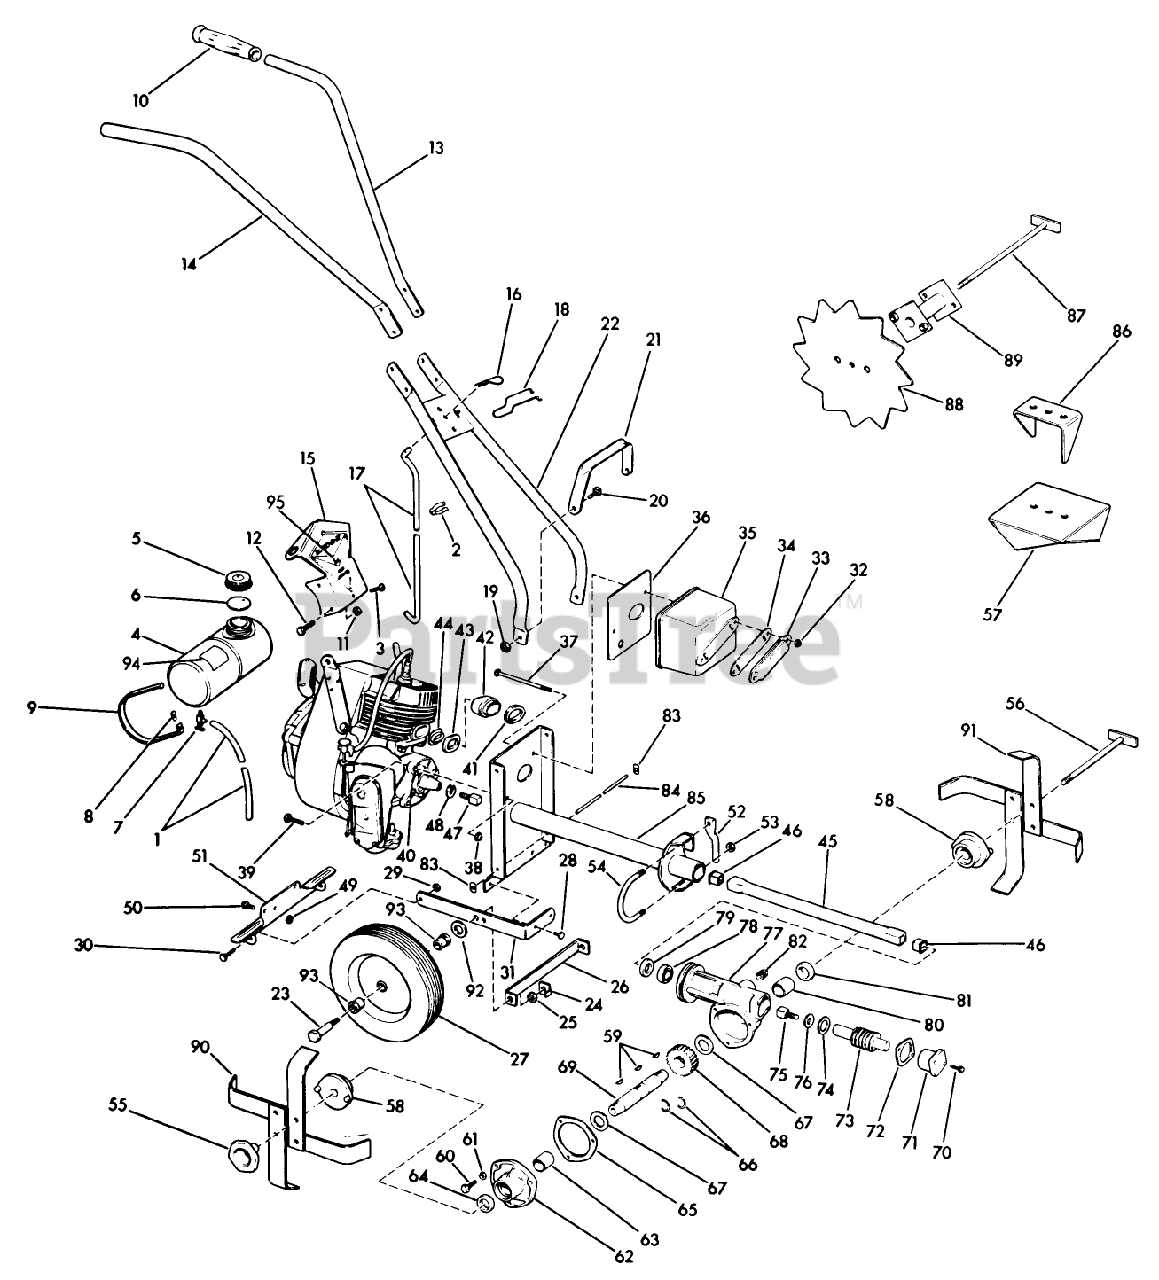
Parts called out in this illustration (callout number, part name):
1	Line-Gas
2	Clip-Gas Line
5	Gas Cap
7	VALVE&SCREEN SM
8	Nut-Speed
9	Tank Strap
12	SCREW S
14	Handle Section-Top, Right
15	Bracket-Upper Handle
17	Rod-Handle Height Adjustment
18	Guide-Starter Rope
19	Nut-Huglok
21	Bracket-Carrier Handle
25	WASHER, LOCK
26	Bracket-Center Wheel Brace
28	Screw-Thread Cutting
31	Bracket-Wheel Attachment
32	LOCKNUT E
33	Chamber-Muffler Transfer
34	Gasket-Muffler Transfer
35	Muffler
36	Gasket-Muffler
38	Nut-Huglok
41	Gasket-Exhaust
42	Sleeve-Exhaust
45	Drive Tube and Bushing Assembly
47	Screw-Square Head
48	WASHER, LOCK
50	SCREW S
51	Bracket-Wheel Scraper
52	Nut-Lever
55	Knob-Tie Rod Assembly
57	Tine-Weeder
60	SCREW S
66	Ring-Retaining
68	Worm Gear
71	Housing Cap
75	Screw-Square Head
83	Nut-Push-on
84	Rod-Wheel Scraper, Fron
86	Tine-Cultivator
88	Edging Disc
94	Decal, Instructions
